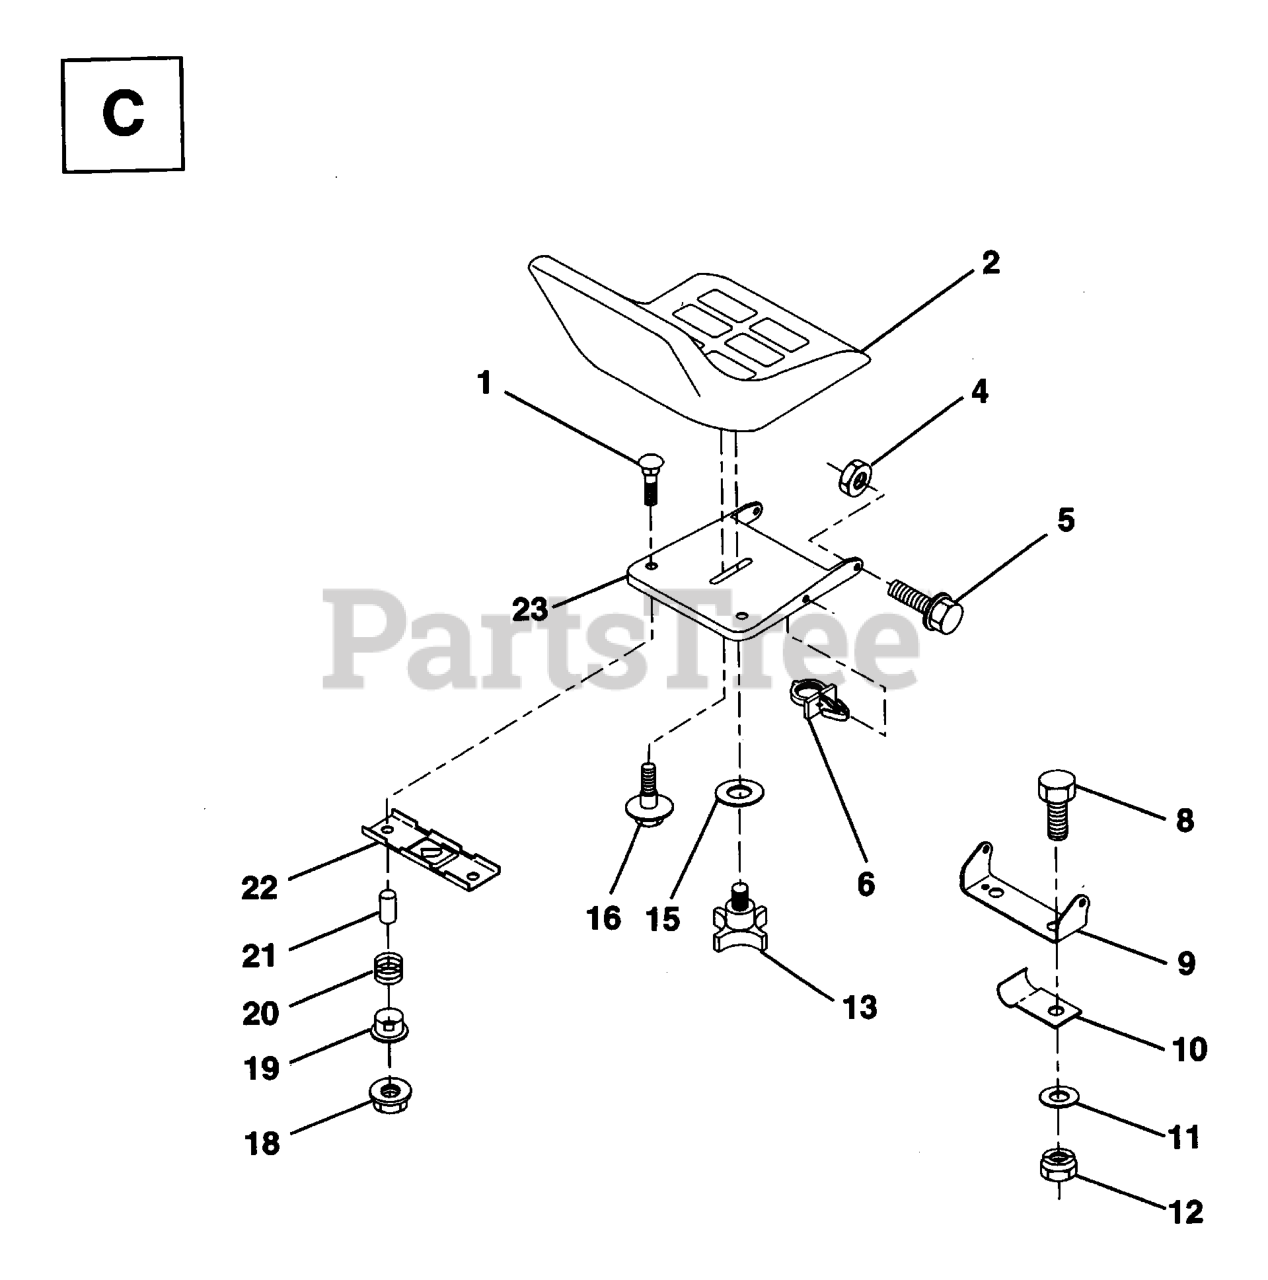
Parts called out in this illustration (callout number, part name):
1	Bolt Rdhd. Sht. Nk 1/4-20 x 1-3/8
2	SEAT
4	NUT.71038.31-18.HEX.NYLOCK
5	BOLT.SHOULDER.5/16-18
8	BOLT
9	SEAT PIVOT BRKT
10	CLIP,INSULATOR
11	WASHER 12/32X2X10GA
12	NUT
13	KNOB 1/2" YT
16	BOLT,SHOULD
18	NUT T
21	SPACER SPLIT 28X.96
22	BRKT SWITCH
23	SEAT PAN
